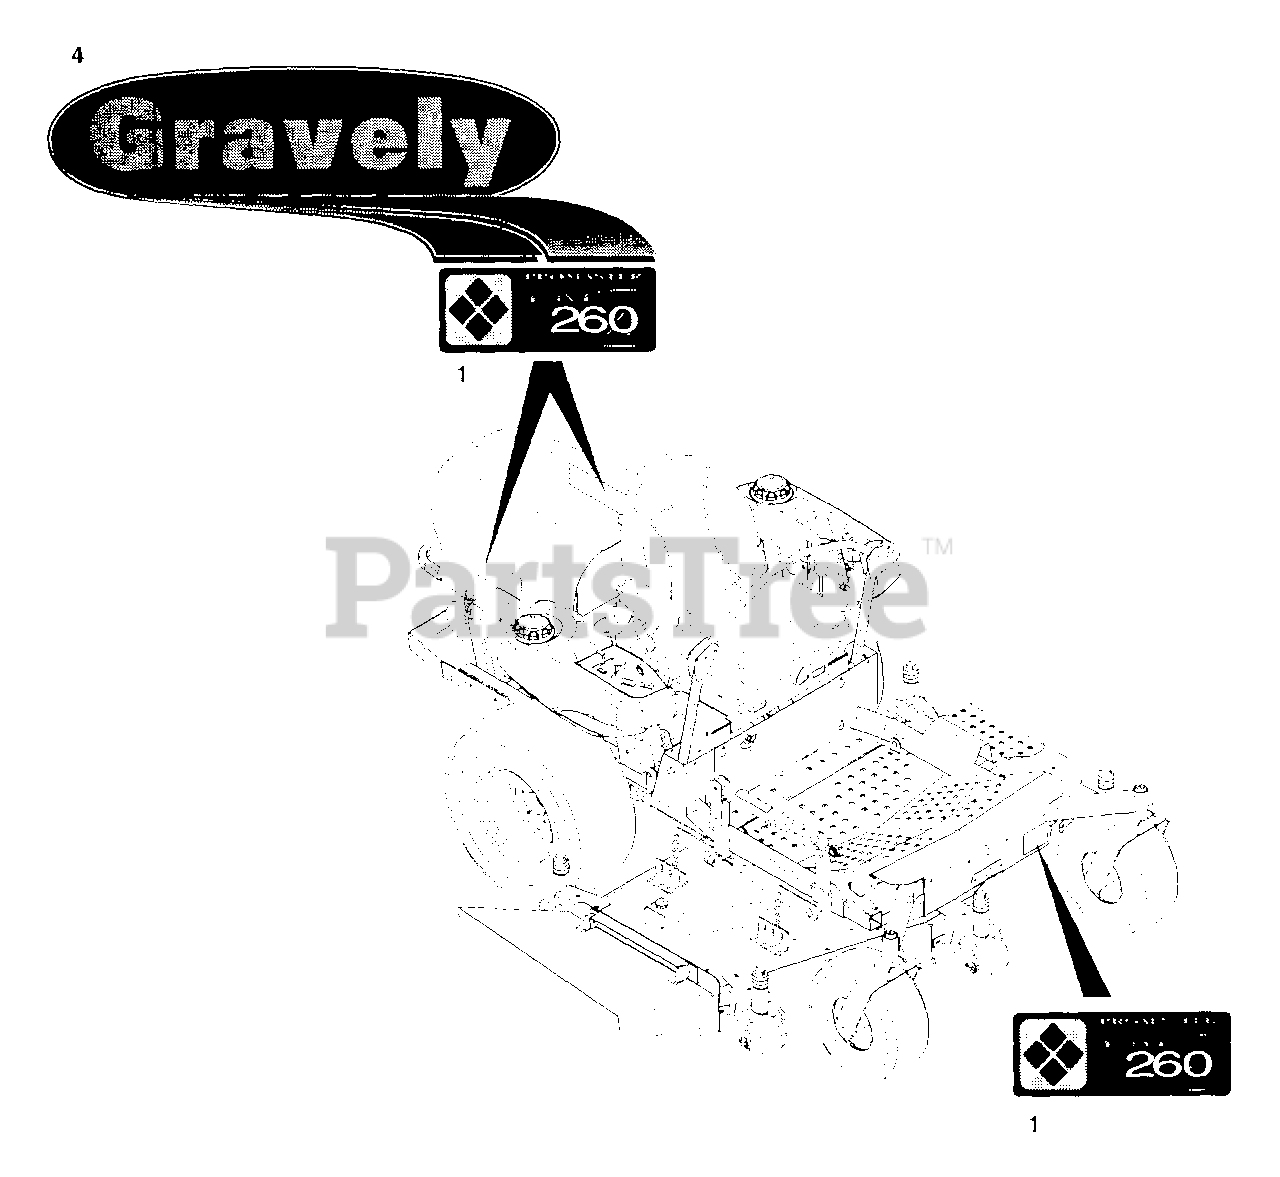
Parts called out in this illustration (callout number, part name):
1	Decal Set PM260Z
2	Decal Set Mower Decks
3	Decal, GRAVELY Belt Diagram
4	Decal Set GRAVELY Logo
